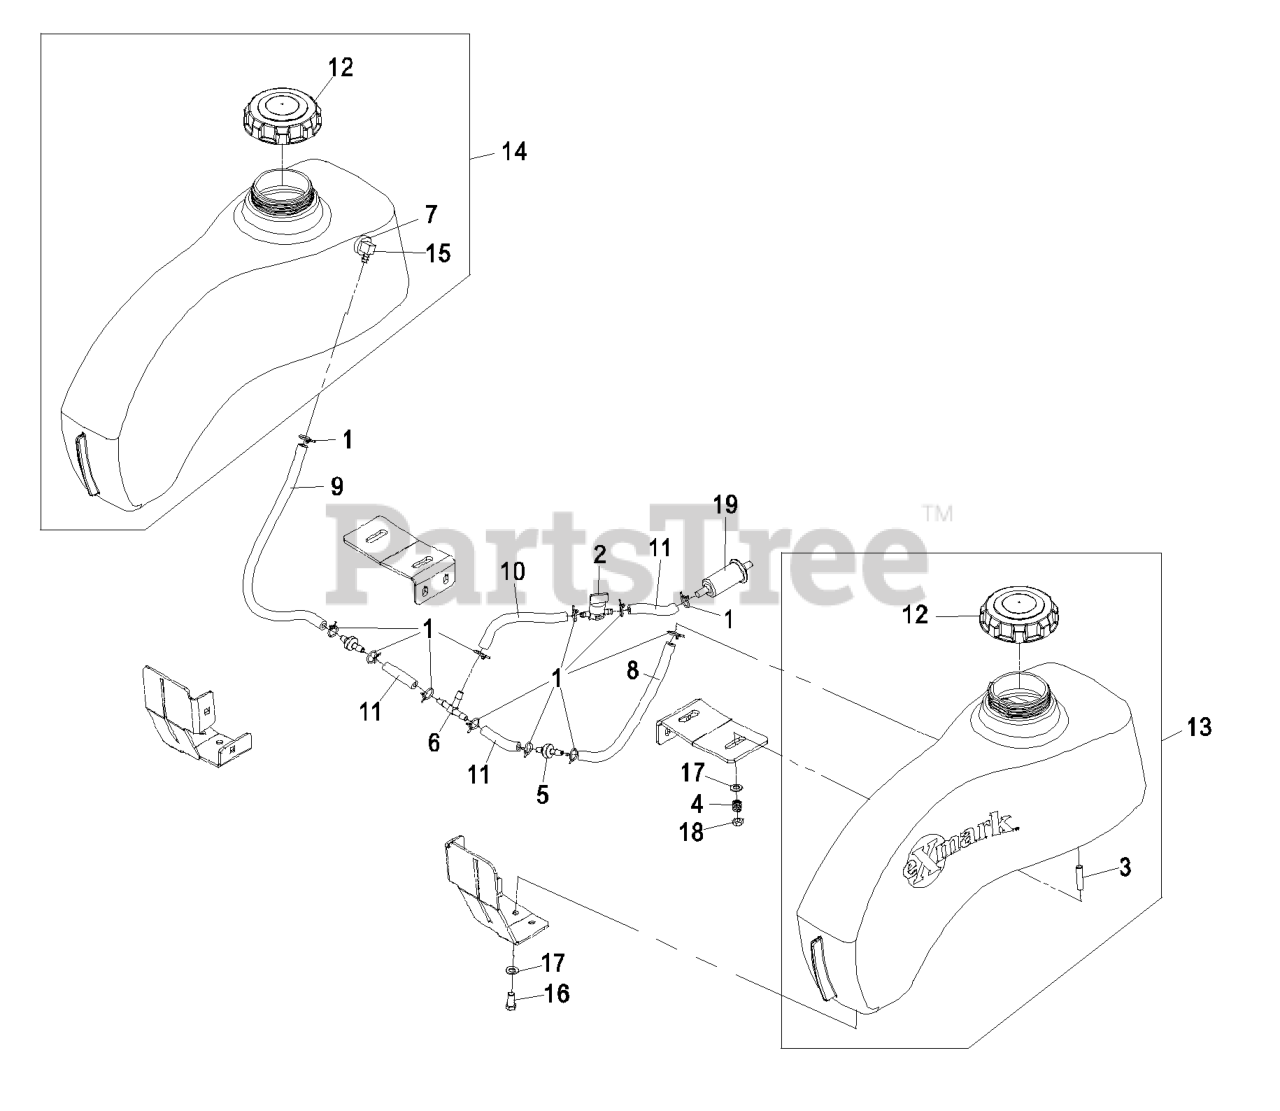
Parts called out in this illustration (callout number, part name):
2	VALVE-FUEL
3	STUD
4	SPRING-TANK, FUEL
5	VALVE-CHECK, FUEL
6	FITTING-TEE, BARBED
7	BUSHING
9	HOSE-FUEL
10	HOSE-FUEL
11	HOSE-FUEL
12	CAP-FUEL, GAS
13	ASM,LH PHAZER TANK W/STUD
14	ASM,PHAZER RH TANK W/STUD
15	FITTING-FUEL (W/LINE AND
16	SCREW-HH
17	WASHER-PLAIN
18	NUT-LOCK, NI
19	Kawasaki Part No. 49019-7001 Fuel Filter
